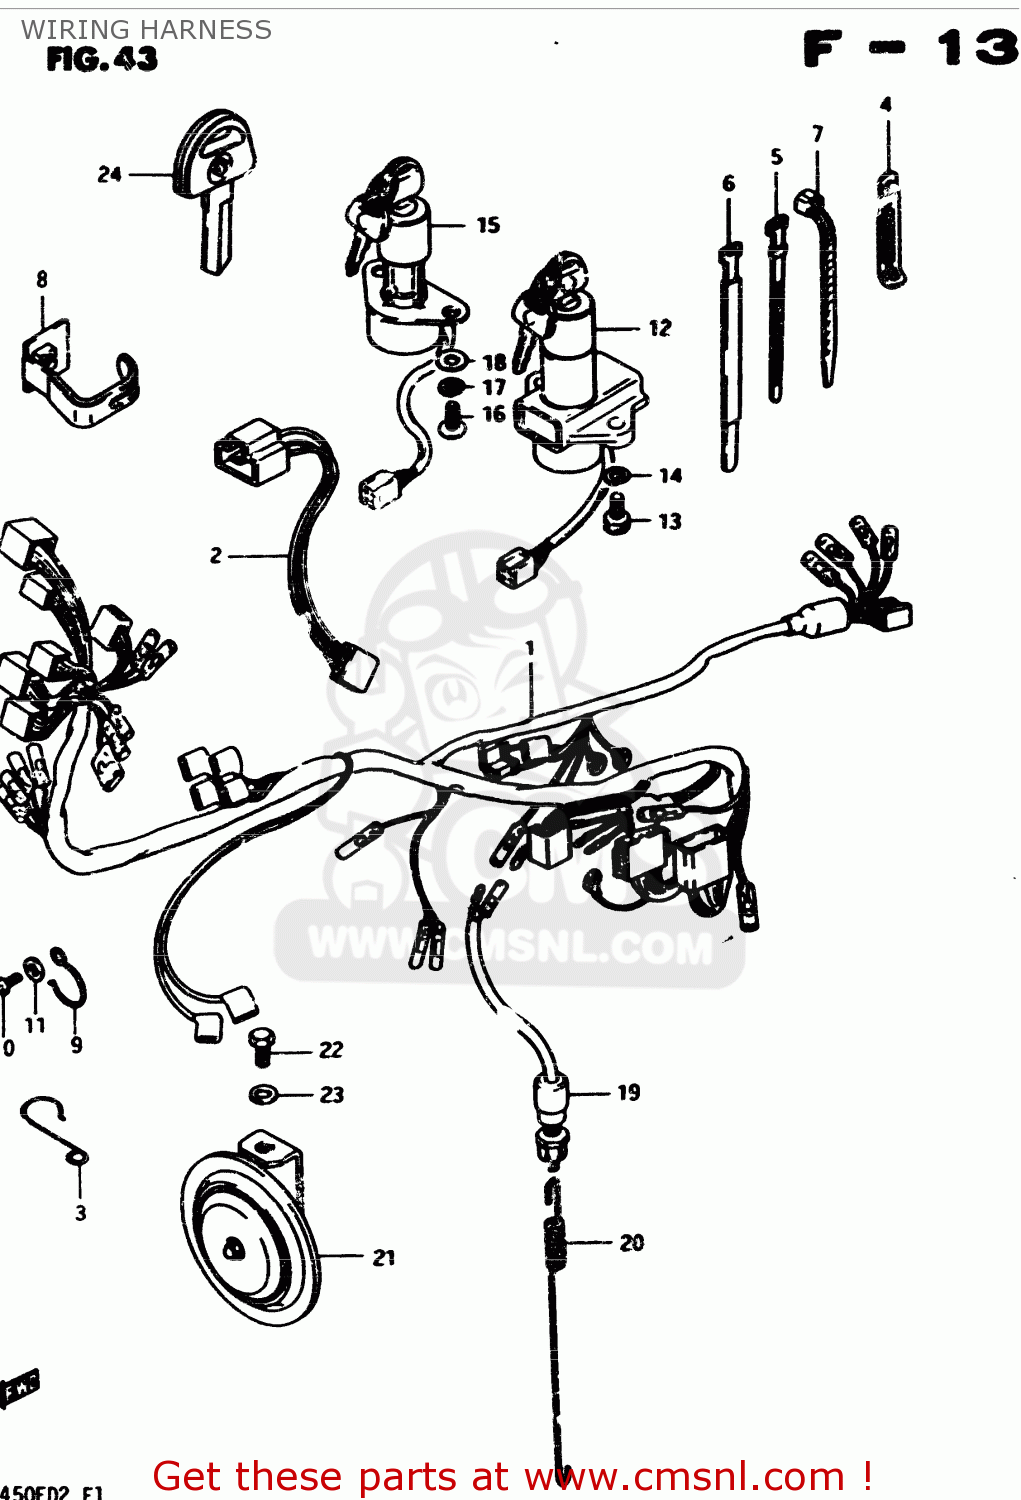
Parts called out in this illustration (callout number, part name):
1	WIRING HARNESS
2	LEAD WIRE,HEADLAMP
3	CLIP,WIRING HARNESS
4	CLAMP L:35
5	CLAMP(L:120)
6	CLAMP
7	CLAMP(L:95)
8	CLAMP,WIRING HARNESS
9	GUIDE,WIRING HARNESS
10	SCREW 6X12
11	WASHER 6MM
12	SWITCH ASSY,IGNITION
13	BOLT
14	LOCK WASHER
15	SWITCH ASSY, IGNITION
16	SCREW
17	LOCK WASHER
18	WASHER
19	SWITCH ASSEMBLY,STOP LAMP
20	SPRING
21	HORN
22	BOLT 8X12
23	WASHER
24	KEY,BLANK
